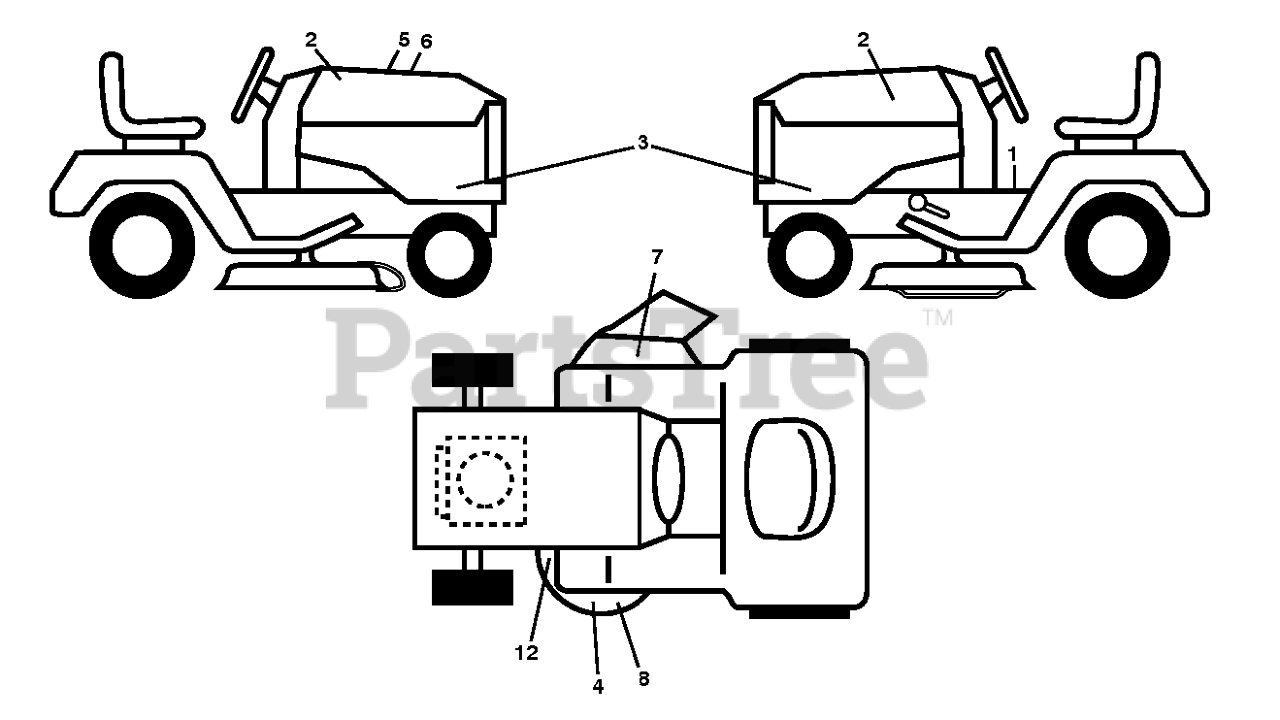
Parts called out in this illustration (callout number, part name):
1	DECAL.FENDER.WARNING.ENGLISH
2	DECAL.BADGE.170MM.TEXTLOGO.
3	DECAL TRACTOR SIDE PANEL DECAL
4	DECAL.MOWER.CAUTION.TENSION.AR
5	DECAL.WARNING.CUST.RESP.E85.
6	DECAL K46.54E.KAW FR651.TLW
7	DECAL, DECK DEFLECTOR, WARNING
12	DECAL.MOWER.SCH.48/54.PREM
